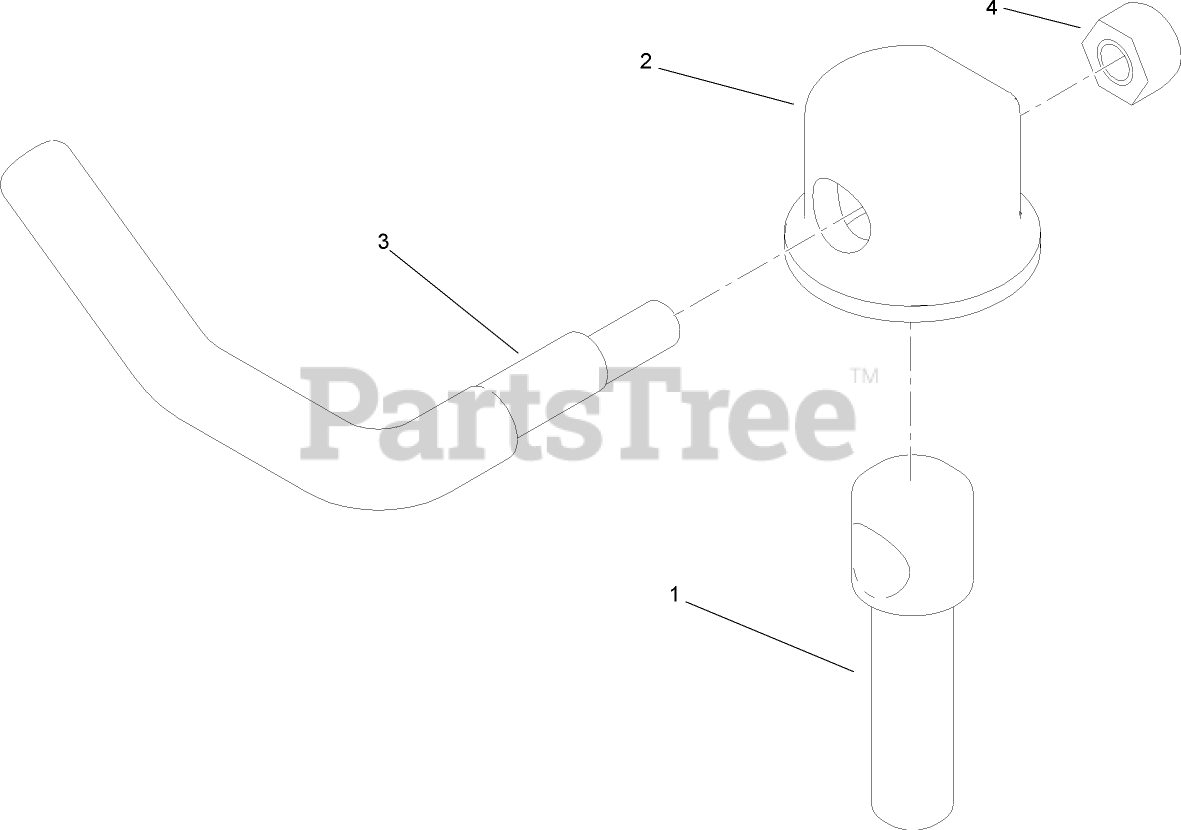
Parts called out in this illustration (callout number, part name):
1	Screw-Lock
2	CAP-LOCK
3	Lever-Lock
4	NUT-LOCK, NI
